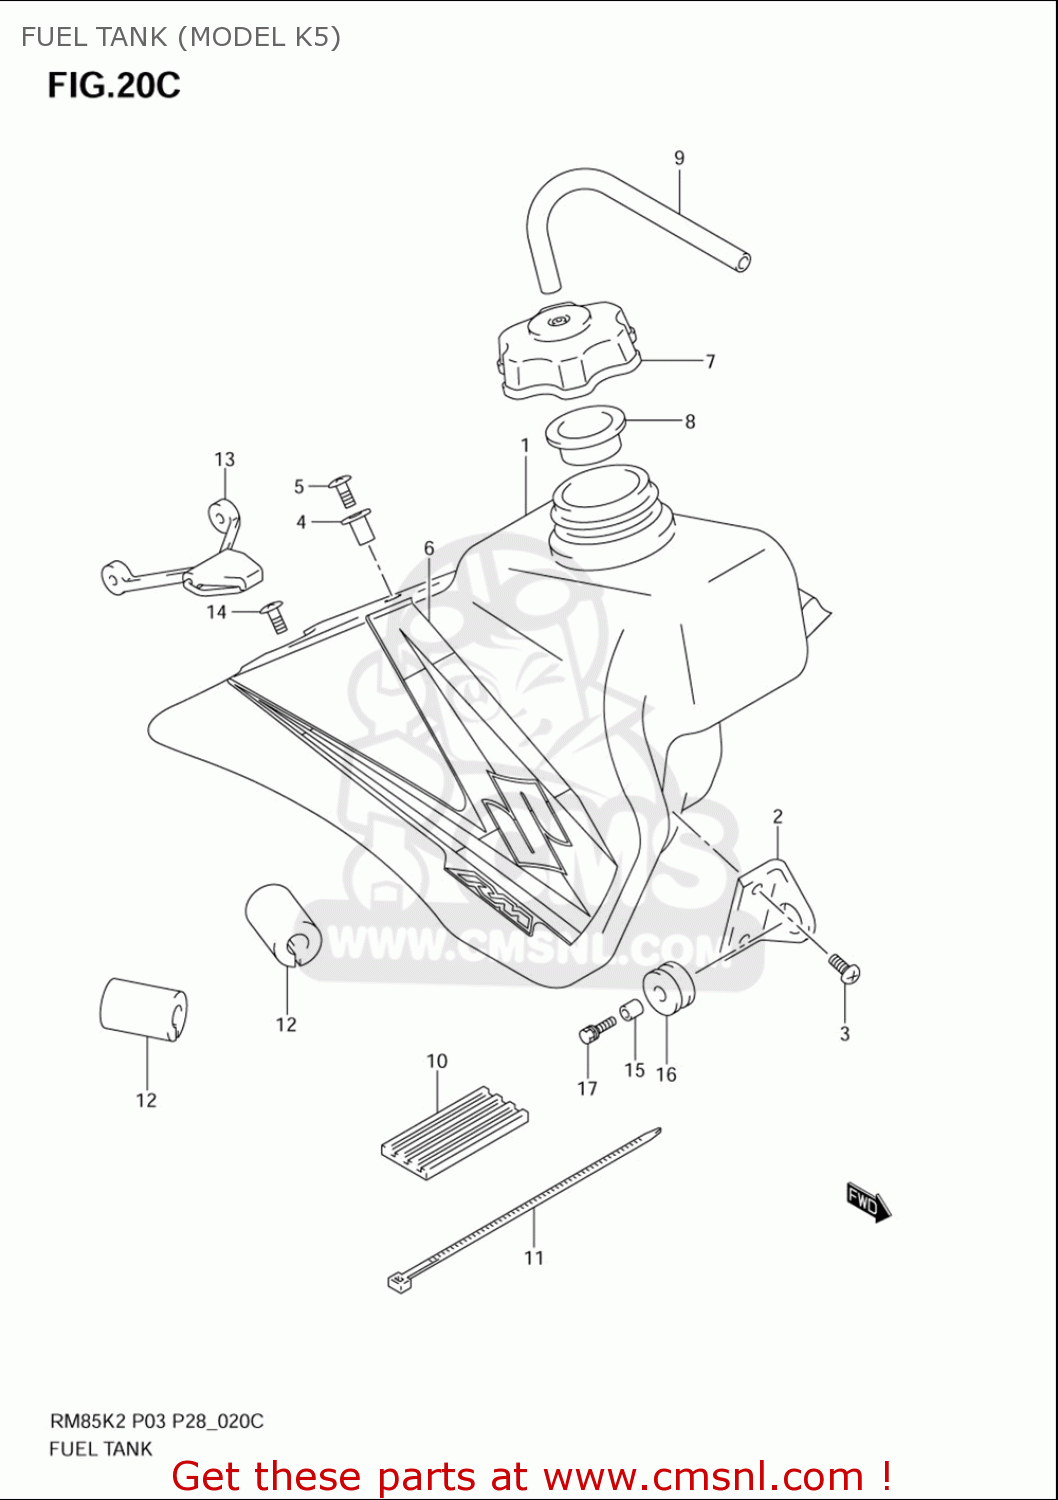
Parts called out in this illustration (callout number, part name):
1	TANK,FUEL(YELLOW)
2	BRACKET,FUEL TANK FR
3	SCREW
4	HOOK,SEAT FR
5	SCREW
6	TAPE SET,FUEL TANK
7	CAP,FUEL TANK FILLER
8	GASKET,CAP (NAS)
9	HOSE(5X8.2X600)
10	CUSHION,FUEL TANK UPR FR
11	CLAMP(L:250)
12	CUSHION,FUEL TANK UPR RR
13	BAND,FUEL TANK RR
14	SCREW(6X13.5)
15	SPACER(6.5X9X13.5)
16	CUSHION,MUFFLER
17	BOLT(6X35)
